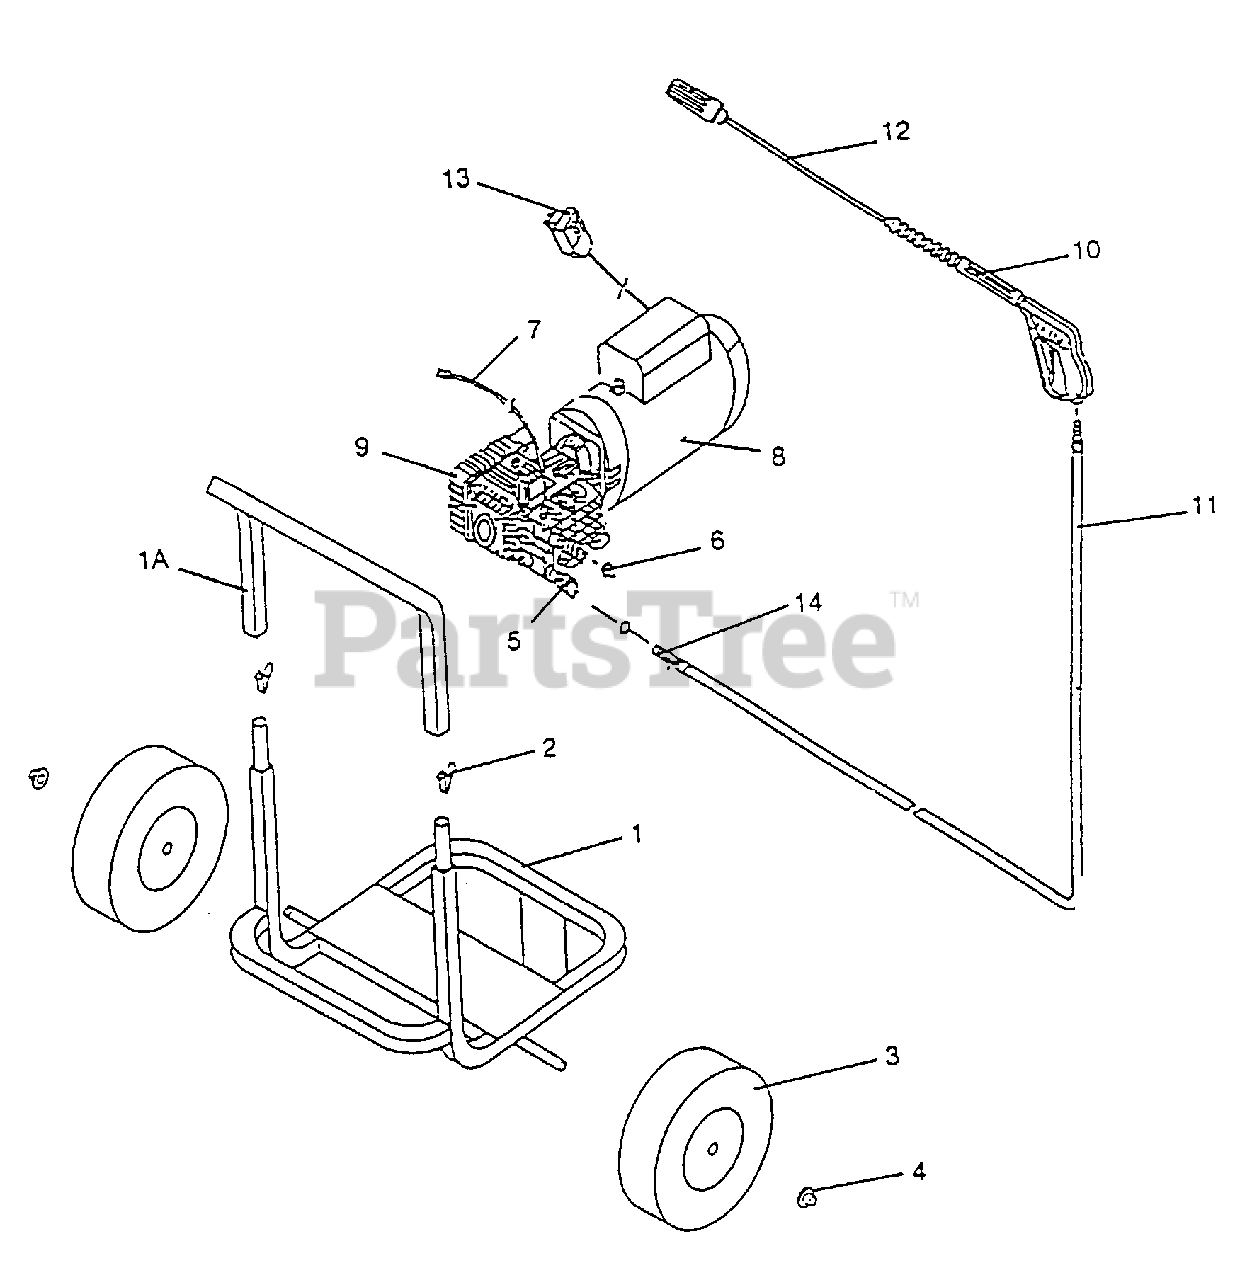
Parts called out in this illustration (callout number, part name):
1A	Handle Bar
2	Valco Spring Buttons
3	Hard Rubber Tires
4	Hub Caps
5	Q.C. Female Socket - 3/8"
6	Hose Screen, Water Inlet
7	5' Nylon Braid Hose w/Chemical Screen
8	1.5 HP electric TEFC
9	General Pump
10	Trigger Gun w/Wand
11	Hose R1 3/8" x 25'
12	Multi Reg Nozzle
13	GFCI
14	Q.C. Plug - 3/8"
